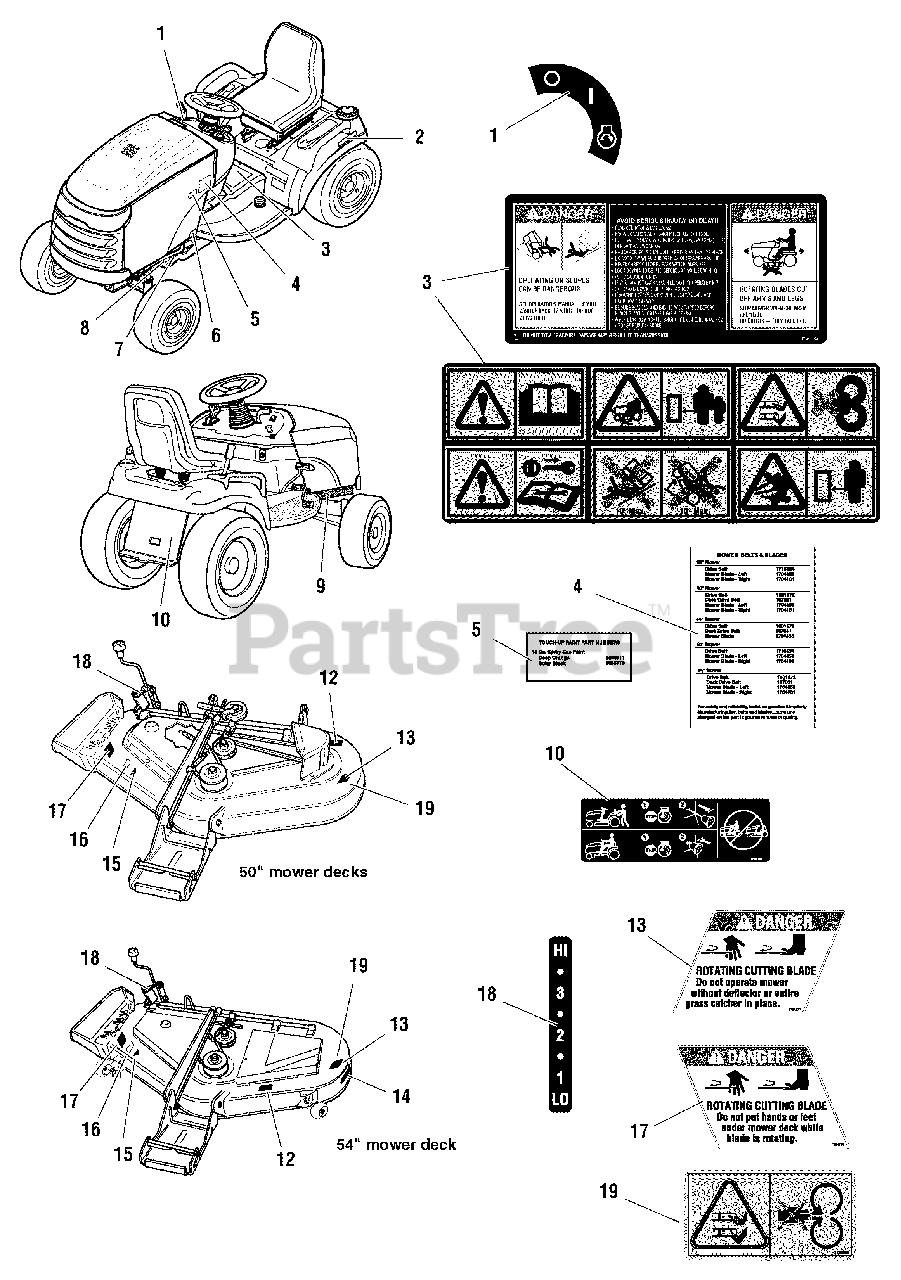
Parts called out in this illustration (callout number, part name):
1	DECAL, Ignition Switch Symbols
2	DECAL, Automatic Controlled Traction
3	DECAL, Tunnel Cover Danger Slopes, Blades
3	DECAL, Tunnel Icons
4	DECAL, Drive Belts, Mower Blades
5	DECAL, Touch Up Paint
6	STICKER, Protection
7	DECAL, I.D. Plate
8	LABEL, Decibel, Power Mass
9	DECAL, Patent
10	DECAL, Transmission Release Valve
12	DECAL, I.D. Plate
13	DECAL, Danger Do Not Operate w/o Deflector
14	DECAL, Free Floating Mower
15	DECAL, OPEI Certified
16	DECAL, 44" Silver on Black w/Stripe
16	DECAL, 50" Silver on Black w/Stripe
16	DECAL, 54" Silver w/Black Stripe
17	DECAL, Danger Do Not Put Hand/Feet In Mower
18	DECAL, 1 2 3 4 5 6, Height of Cut White/Black
19	DECAL, Danger Rotating Blade
